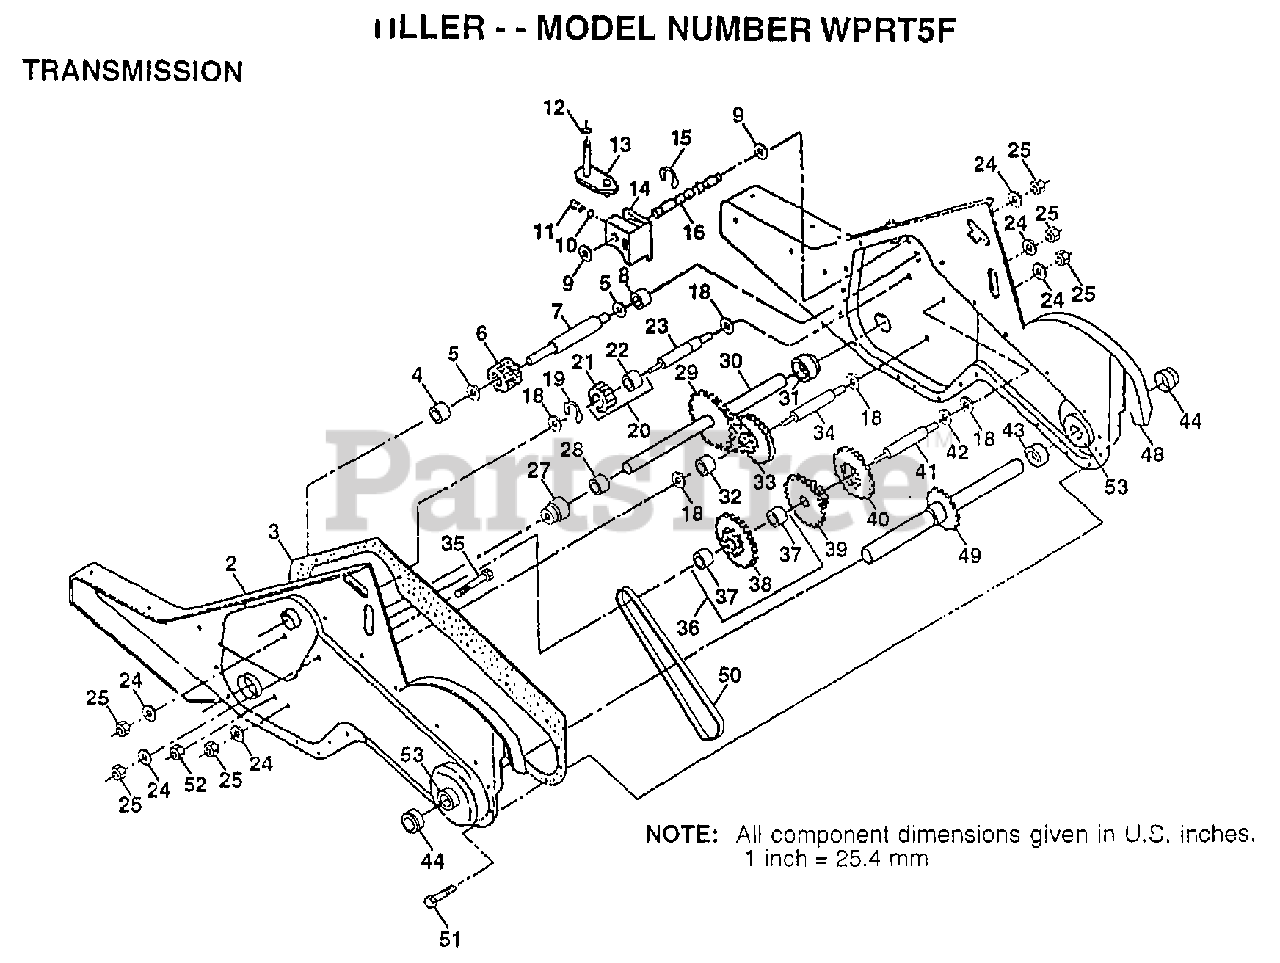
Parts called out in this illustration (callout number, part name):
2	GEARCASE LH W/BRG
3	GASKET TI
4	NEEDLE BRNG LT
5	"T, BEARING"
6	GEAR PINION INPUT
7	"SHAFT.INPUT.""D"""
8	"TI, BEARING"
9	WASHER SEAL
11	SPRING-SHIFT CRT
12	O-RING TI
13	BRACKET ASM SHIFT
14	SHIFT FORK TI
15	KLIP RING
16	SHAFT.SHIFTER
18	WASHER
19	KLIP RING
20	GEAR ASSY CRT
21	GEAR-REV IDLR CRT
22	NEEDLE BEARING TI
23	SHAFT CRT
24	LOCKWASHER
25	NUT.ASF.HEX.7/16
27	BEARING.SHAFT.LH.
28	BUSHING TI
29	CHAIN CRT
30	GROUND SHAFT ASSY
31	BEARING.SHAFT.RH.
32	SPACER TI
33	SPRCKT 8 GEAR CRT
34	SHFT 2ND RED. CRT
35	SCRW WHIZ LOK CRT
36	SPROCKET.ASM.W/BR
37	BEARING
39	GEAR TI
40	GEAR TI
41	REDUCTION SHFT TI
42	BRNG RACE
43	SPACER TI
44	SEAL ASM-OIL
48	GEARCASE RH W/BRG
49	TINE SHAFT
50	CHAIN.50 LINK TI
51	SCREW
52	NUT.HEX.5/16-18
